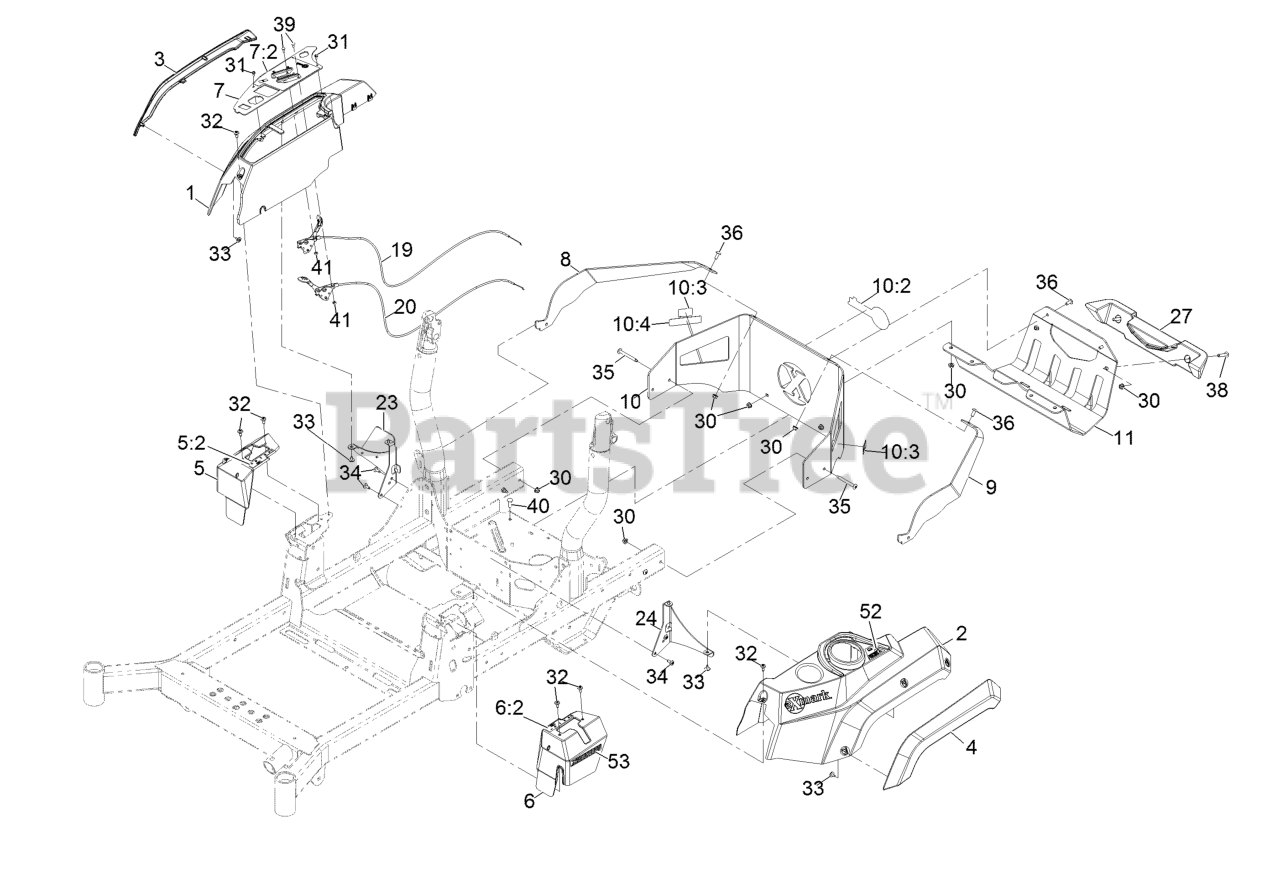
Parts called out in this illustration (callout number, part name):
1	Console-Exmark, RH
2	Console, LH
3	Fender-RH
4	Fender-LH
5	Cover-Control, Motion (RH)
5:2	Decal-Control, Motion (RH)
6	Cover-Control, Motion (LH)
6:2	Decal-Control, Motion (LH)
7	Ctrl Panel ASM W/Decal
7:2	Decal-Control Panel
8	Support-Upper, RH
9	Support-Upper, LH
10	Rear Guard ASM
10:2	Decal-Exmark Logo
10:3	Decal-Warning
10:4	Decal-Arrester, Spark
11	Guard-Muffler
19	Cable-Control, Choke
20	Cable-Control, Throttle
23	Support-Console, RH
24	Bracket-Console, LH
30	Nut-Nyloc 5/16-18 Flg
31	Screw-HWH #10-14 X 1/2
32	Screw-1/4-20 X 1/2 Tf Torx Plus
33	Screw-HWH #10-14 X 1/2 Torx
34	Screw-1/4-20 X .65 Torx Plus
35	Screw-Truss HD 5/16-18 X 2 3/4 Torx Plus
36	Screw-Truss HD 5/16-18 X 3/4 Torx Plus
38	Screw-Truss HD 5-16-18 X 1 1/2 Torx Plus
39	Bolt-Carriage #10-24 X 1/2
40	Bolt-Carriage 5/16-18 X 1 Sp
41	Nut-Nyloc #10-24
52	Decal-Fill, Fuel
53	Decal-X-Series
